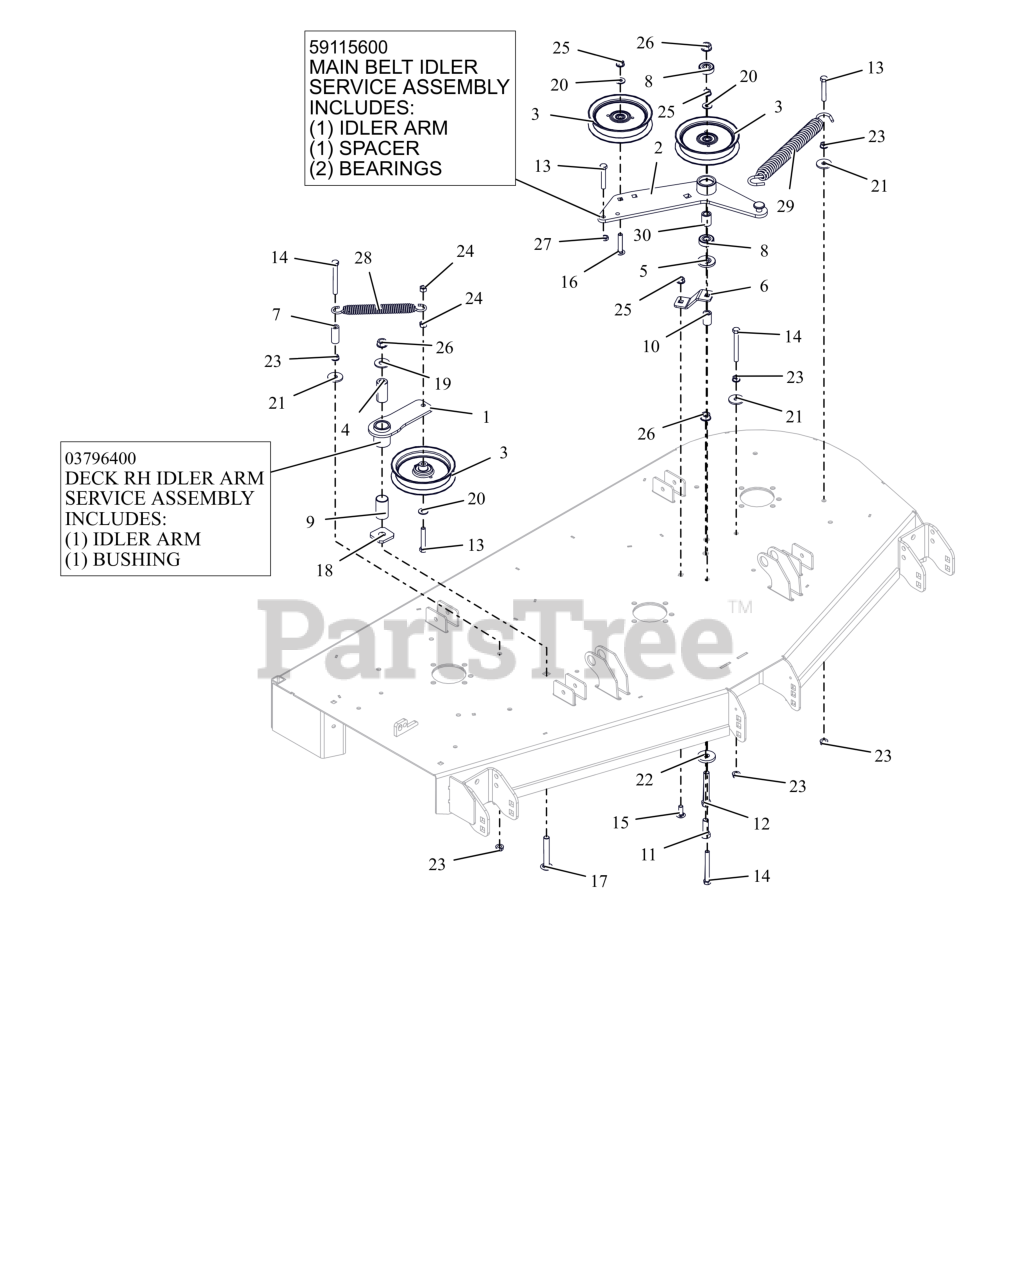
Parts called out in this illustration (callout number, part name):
1	WMT, IDLER ARM - BLACK
1	ASM, IDLER ARM (DECK)
2	WLDMT, DECK PTO IDLR ARM
3	IDLER, FLAT 5.00"
4	BSHG, SPCR .502X.997X2.03 PM
5	SPACER, IDLER ARM
6	PTO FIXED IDLER MTG BRKT -RED
7	HOSE, .38 X 1.65
8	BRG-BALL .500X1.38X.437
9	BSHG, 1.00X1.125X1.937
10	BUSHING, SLV .380X.750X1.190
11	BLT,HEX .50-13X1.50 G5 ZCC
12	BLT,HEX .50-13X3.25 G5 ZCC
13	BLT,HEX .38-16X2.25 G5 ZCC
14	BLT, HEX .38-16X3.25 G5 ZCC
15	BLT,RHSSN .38-16X1.00 G5 ZCC
16	BLT,RHSSN.375-16X2.00 G5 ZCC
17	BTL,RHSSN .500-13 X 3.25 G5 ZCC
18	WSHR-FLT .640X1.75X.250
19	WSHR,FLT .563X1.375X.109 ZCC
20	WSHR,FLT .375X.875X.083 ZCC
21	WSHR,FLT .406X1.375X.135 ZCC
22	WSHR-FL-STL 0.557X1.625X0.25 ZCC
23	NUT, SPNLK-FLG .38-16 G5 ZCC
24	NUT-LK-CTR .38-16 ZC120
25	NUT-LK-CTR-FLG .375-16 GF ZCC
26	NUT-LK-CTR-FLG .500-13 GG ZCC
27	NUT-JAM .375-16 G2 ZCC
28	SPRING, EXTENSION
29	SPRING, EXTENSION
30	SPACER .510 X .75 X 1.1485
